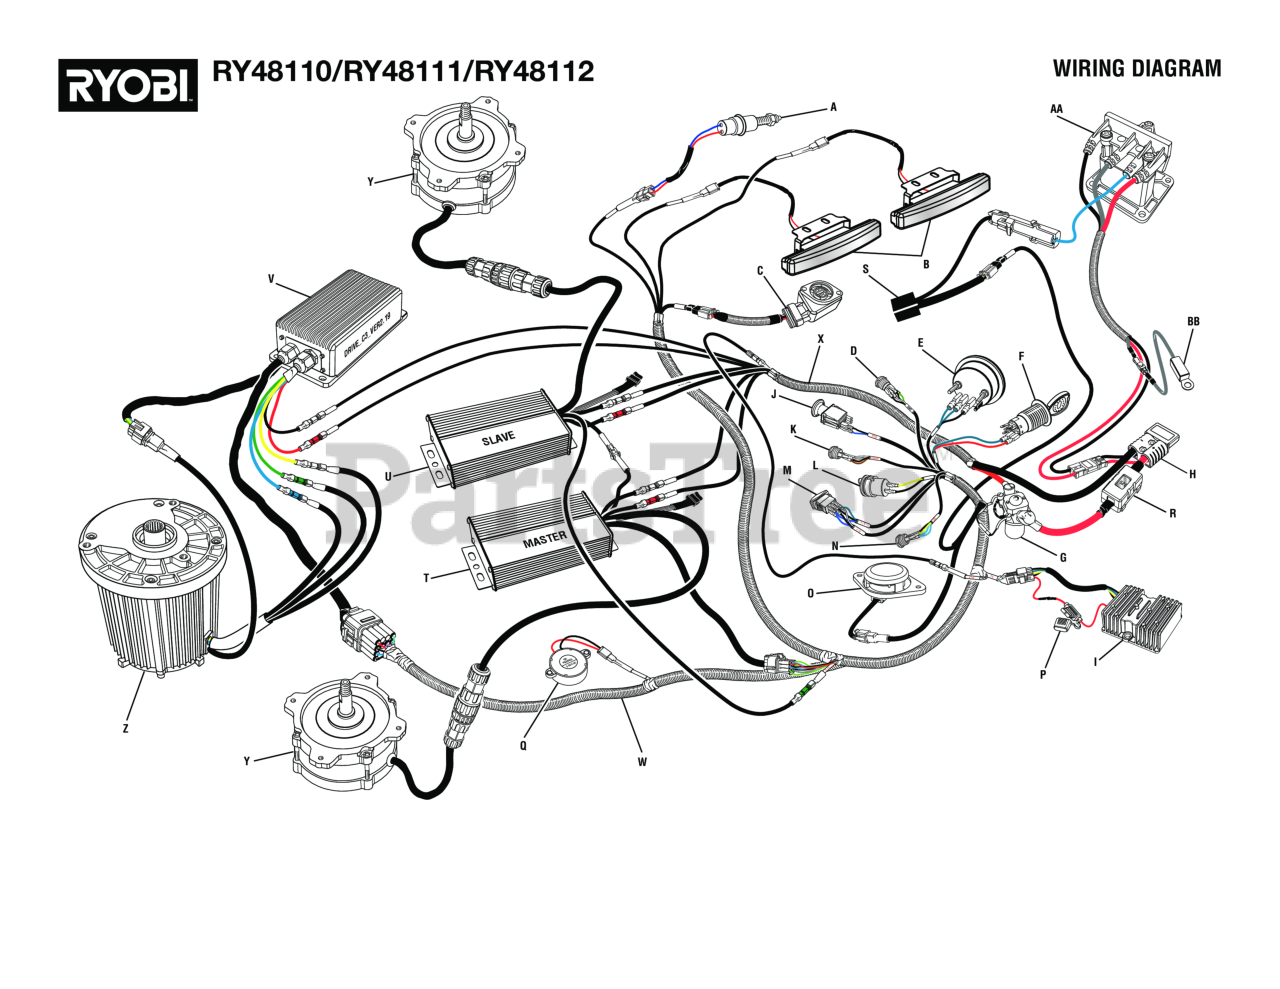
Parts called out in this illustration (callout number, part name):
A	Brake Switch
B	Headlights
C	Accelerator
D	RMO
E	Battery Gauge
F	Switch w/Key
G	Relay
H	Battery Connector
I	12 Volt Power Converter
J	Blade PTO
K	Cruise
L	USB
M	Forward/Netural/Reverse
N	Headlight Switch
O	Seat Switch
P	5 Amp Fuse
Q	Beeper
R	125 Amp Fuse
S	Charger Lockout Circuit
T	Master Deck Motor Controller
U	Slave Deck Motor Controller
V	Drive Motor Controller
W	Main Wiring Harness
X	Sub Wiring Harness
Y	Deck Motor
Z	Drive Motor
AA	Charger Port
BB	Temperature Sensor
